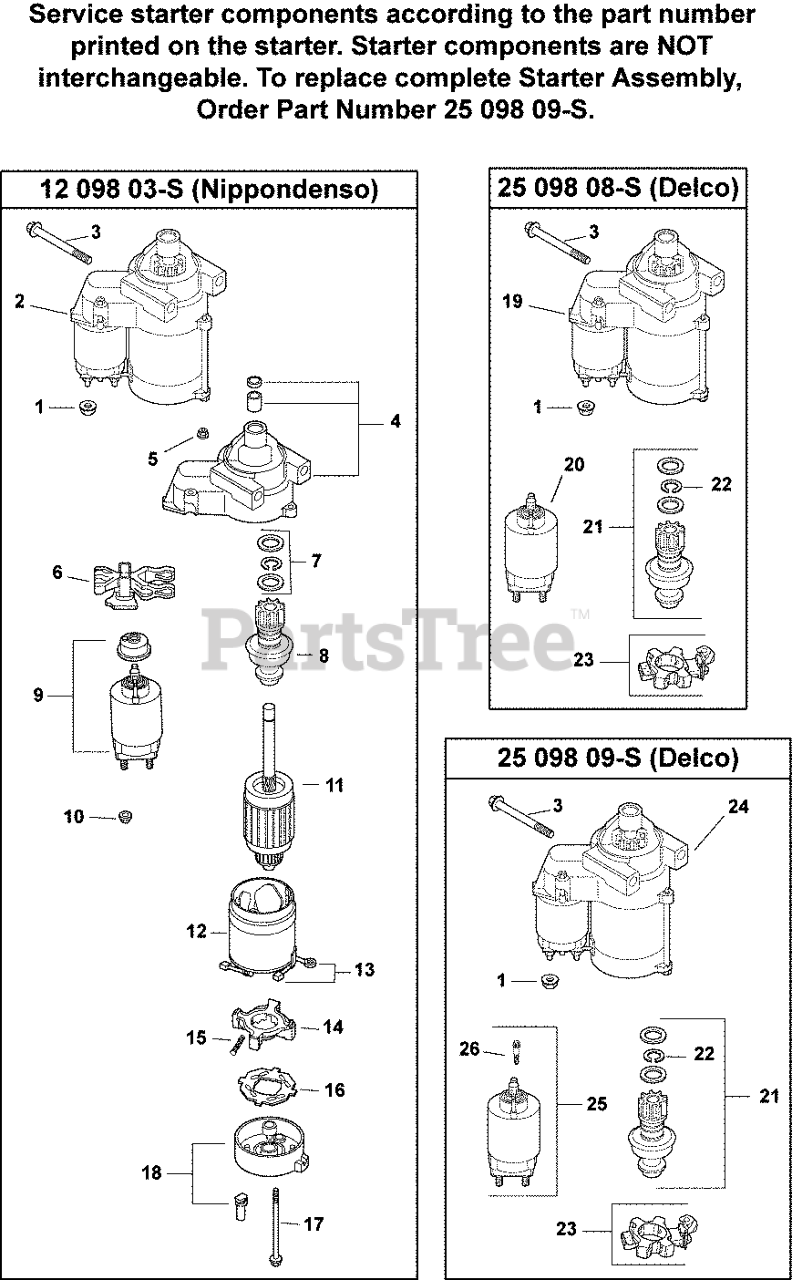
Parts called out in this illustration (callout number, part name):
1	NUT, FLG M8X1.25
3	SCREW - USE M-851080-S
4	DRIVE END CAP
6	LEVER, DRIVE
7	KIT, STARTER REPAIR
8	DRIVE PINION
11	ARMATURE - DISCONTINUED
12	FRAME W/BRUSHES - DISCONTINUED
13	BRUSH & SPRING KIT
14	BRUSH HOLDER
15	SPRING, BRUSH
16	INSULATOR
17	THRU BOLT
18	COMMUTATOR END CAP - DISCONTINUED
19	STARTER, SOLENOID SHIFT-USE 25 098 11-S
20	SOLENOID-(#DSC)
21	KIT, STARTER PINION
22	RING, RETAINING-(#DSC)
23	KIT, BRUSH HOLDER
24	STARTER, SOLENOID SHIFT-USE 25 098 11-S
25	KIT, SOLENOID
26	SCREW, EXTERNAL TORX HEAD
